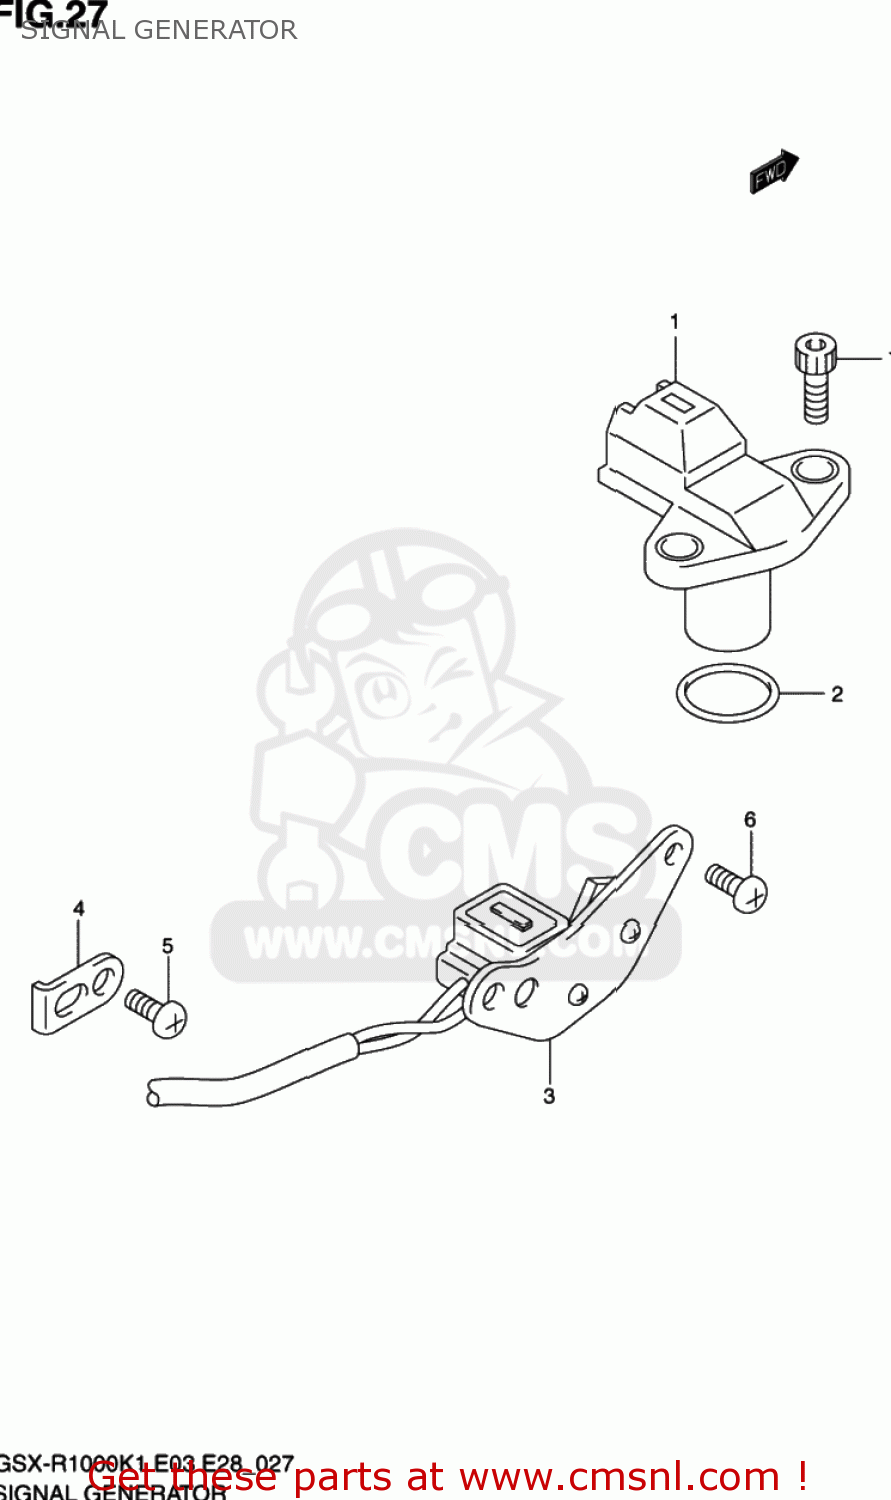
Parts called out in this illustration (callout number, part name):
1	SENSOR ASSY,CAM POSITION
2	PACKING (NAS)
3	STARTER SIGNAL GENERATOR
4	CLAMP,SIGNAL GENERATORERATOR
5	SCREW
6	SCREW
7	BOLT,OIL FILLE
